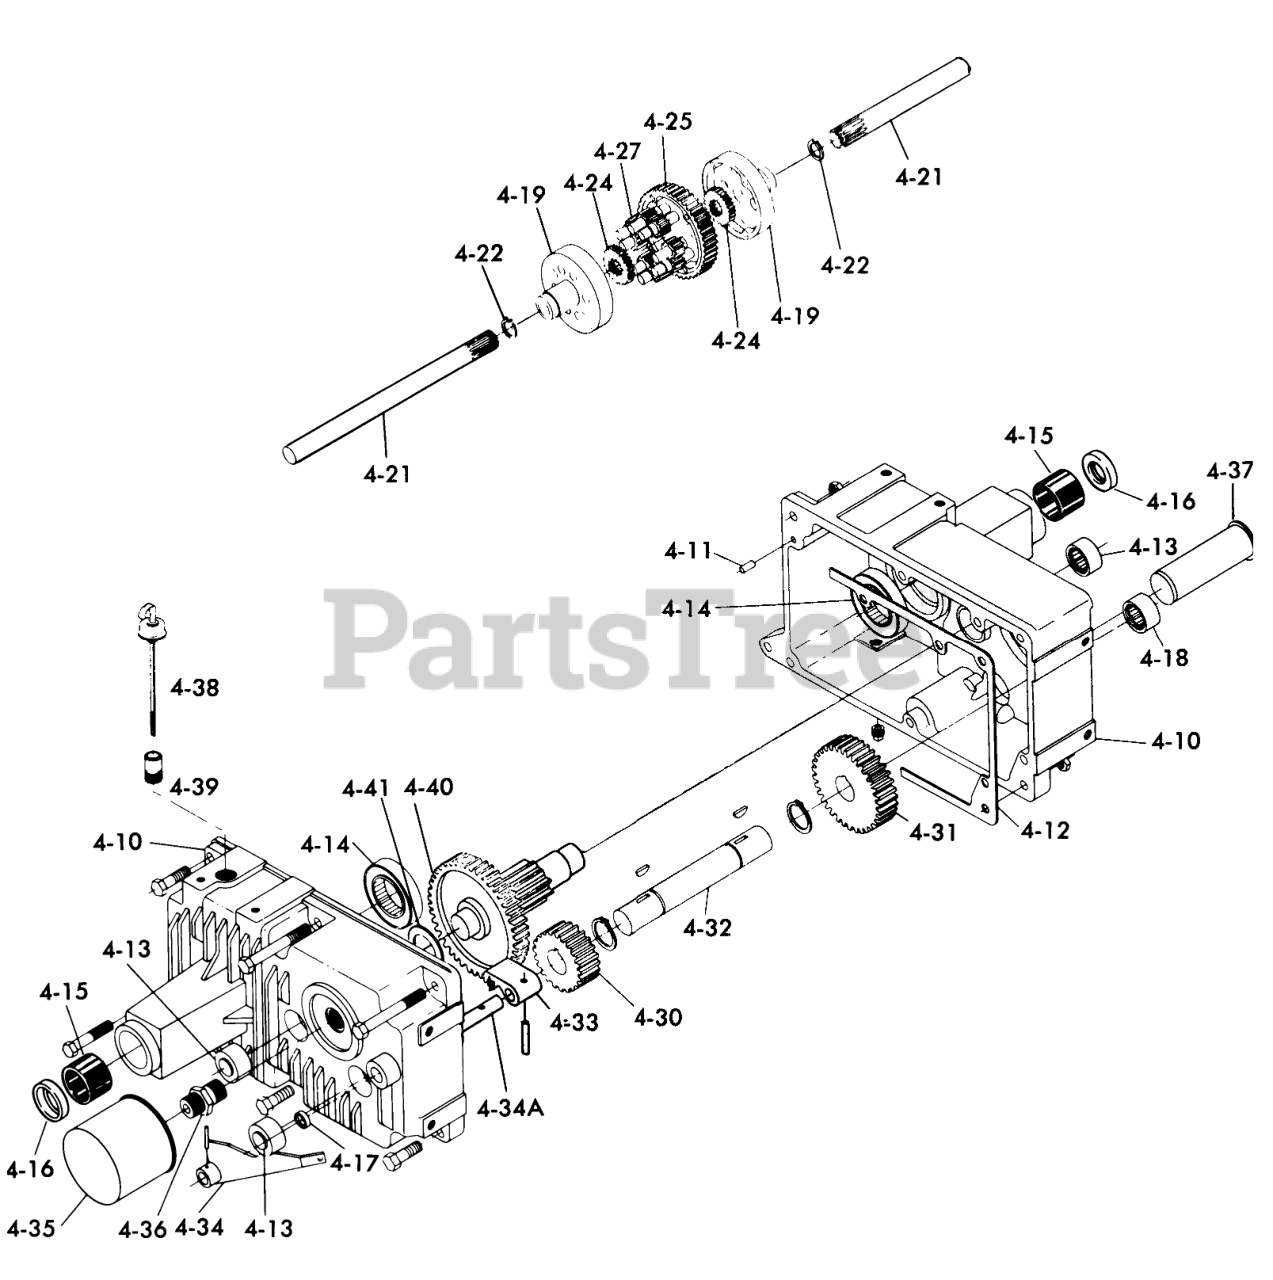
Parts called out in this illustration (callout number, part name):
4-10	RH TRANSMISSION CASE
4-10	Case LH
4-10	PLUG 1/4 PIPE ALLEN
4-10	H H C S
4-10	HHCS
4-10	Bolt
4-10	Washer
4-10	Nut
4-10	BOLT
4-11	PIN-DOWEL
4-12	GASKET
4-13	BEARING-NEEDLE
4-14	BALL BRG 1 1/2 I.D.
4-15	Bearing-Axle
4-16	SEAL-OIL
4-17	SEAL BRAKE SHAFT
4-18	Needle Bearing
4-19	DIFFERENTIAL END CAP
4-19	BOLT-HEX
4-19	NUT
4-21	AXLE-REAR
4-22	RING-SNAP
4-24	GEAR-AXLE DIFFERENTIAL
4-25	GEAR-DIFFERENTIAL RING, 43T
4-27	GEAR-PINION, 11T
4-30	GEAR 24T
4-31	Gear 44T
4-32	SHAFT GEAR
4-32	Snap Ring
4-32	Key
4-33	PAWL PARKING
4-34	Brake Lever
4-34A	Shaft
4-34A	Pin-Roll
4-34A	PIN-ROLL
4-35	Filter
4-36	FITTING
4-37	Strainer
4-38	Dipstick
4-39	Nipple
4-40	GEAR ASSY
4-40	PINION SHAFT
4-40	Gear-42T
4-41	WASHER-THRUST
